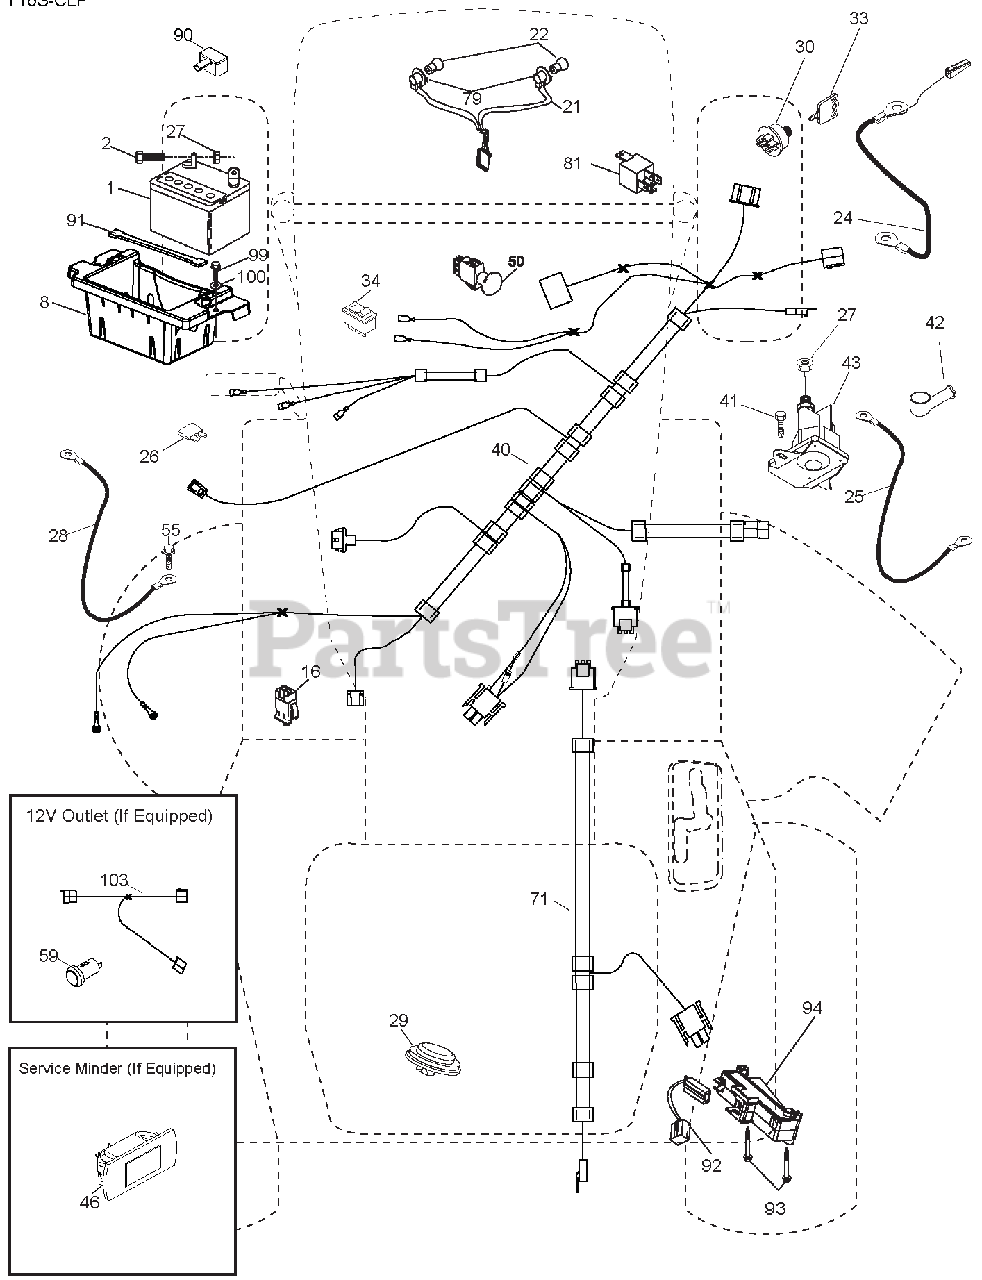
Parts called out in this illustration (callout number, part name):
1	BATTERY.12.VOLT.28.AMP.WET
2	BOLT.HEX.HD.1/4-20UNC X 3/4
8	BATTERY.MOUNT.FRONT.TRAY
16	SWITCH.INTERLOCK.NONO.GRAY
21	HARNESS ASM.LIGHT.22"(4152J)
22	BULB.LIGHT.#1156
24	CABLE BATTERY
25	CABLE.STARTER
26	FUSE.20 AMP.
27	Nut, Keps Hex 1/4-20 unc
28	CABLE.BLACK
29	SWITCH.SEAT.DELTA.OPC.9LB.
30	SWITCH.IGN.DLTA.P-IN.ROS
33	KEY/CHAIN.BLISTER PACK.GEN.USA
34	SWITCH.LIGHT/RESET.B/B/RED.
40	HARNESS IGN. ELECTRIC RELAY
41	Screw 1/4-20 x 1/2
42	COVER.TERMINAL.RED
43	SOLENOID.W/BRASS PLUNGER.2005
46	HOUR METER
50	SWITCH.PTO.8 TERMINAL.BLACK
55	SCREW.5/16-18X3/4.SMGML.TAP/R
71	HARNESS.IGN.CHASSIS.TEX
79	SOCKET ASM.BULB.TWISTLOCK
81	RELAY HARNESS SEALED
90	COVER TERMINAL BATTERY FR. TEX
91	STRAP.BATTERY.MOUNT.FRONT
92	HARNESS.PIGTAIL.CONSLE.ROS.MLK
93	SCREW.PLASTITE.10-14 X 2.0
94	MODUAL REVERSE ROS
99	SCREW.HEXWSH.THDROL.1/4-20X3/4
100	WASHER.9/32 X 7/8 X 16GA.
